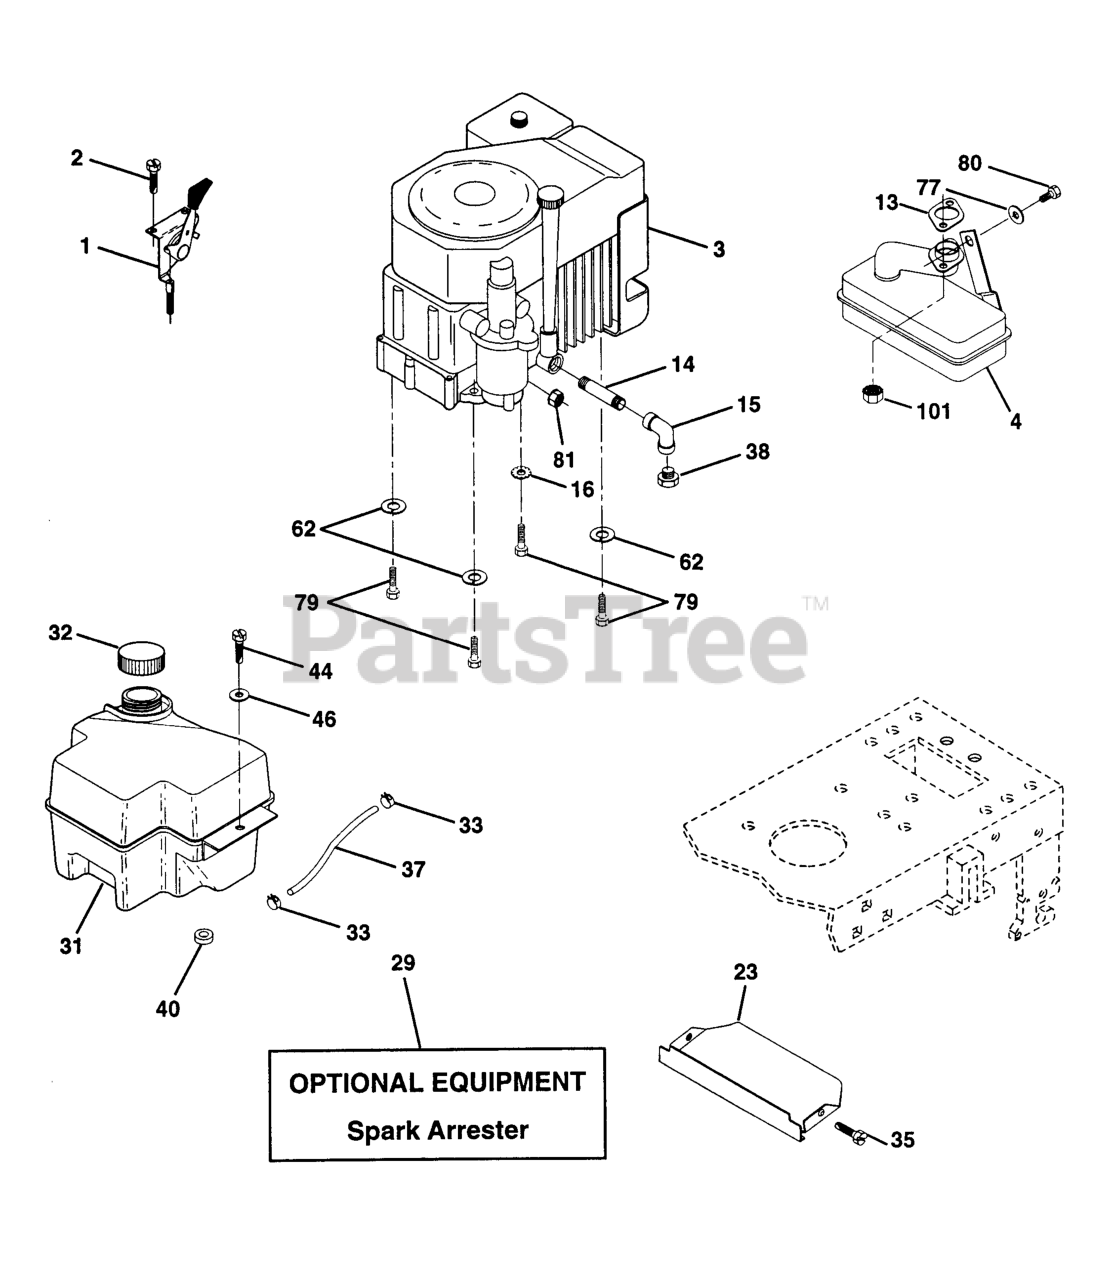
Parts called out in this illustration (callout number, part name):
1	CONTROL SWITCH 27 LH
2	SCREW LT
4	MUFFLER LT 12.5
13	KOHLER GASKET
14	Nipple Pipe 3/8 Npt X 3-1/2
15	ELBOW
16	WASHER EXT TOOTH LOCK 5/16
29	KIT.SPARK ARRESTOR 794945 B&S
31	FUEL TANK
32	FUEL CAP
33	HOSE CLAMP
35	SCREW.THDROL.5/16-18X3/4.TTY
37	LINE.FUEL.20
38	Plug Oil Drain
40	BUSHING.SNAP.NYL.BLK.
44	SCREW HEX CRT
46	WASHER
62	WASHER.LOCK.HVY.HLCL.SPR.5/16
77	WASHER
79	BOLT, HEX
80	Bolt Hex Hd 5/16-18 UNC x 1/2
81	NUT FLANGE 1/4-20 STARTER NUT
101	FLANGE NUT
